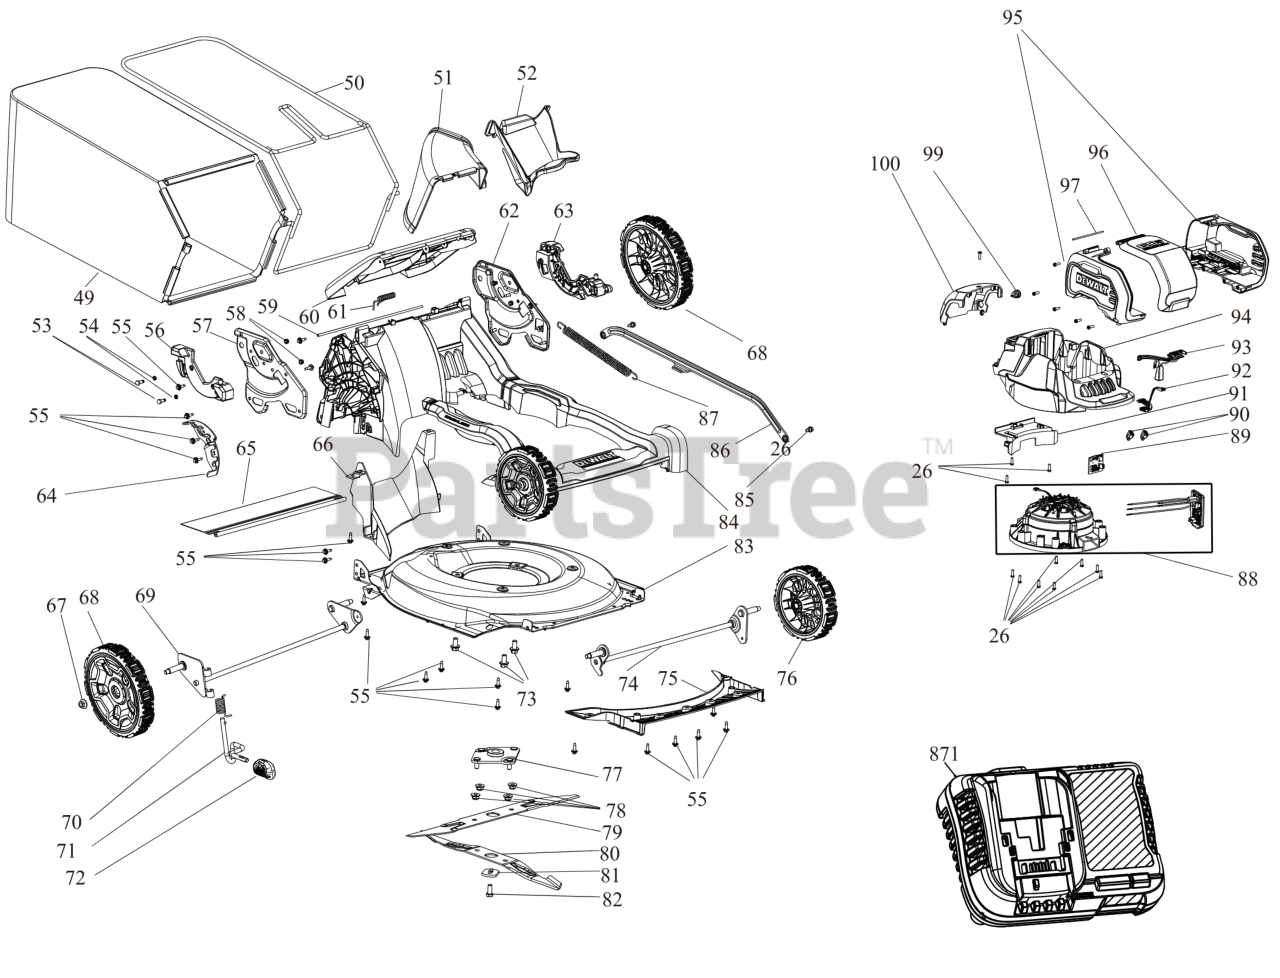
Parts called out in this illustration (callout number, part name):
1	BUTTON
2	SPRING
3	SCREW
5	COVER
6	CONTROL
8	BUTTOM
9	HANDLE SA
10	SWITCH
11	WIRE HARNESS
13	SCREW M6X45-T30-THD FRM
14	COVER
16	SWITCH COVER
17	CATCH
20	SPRING TORSION
21	STRIP
22	SLEEVE
23	TUBE UPPER
25	TUBE LOWER
26	SCREW M4.55X16 T20-PLAS THD FRM
27	SLEEVE
29	WASHER
30	SCREW
33	SPRING
35	SPRING
36	SPRING
37	SPRING
40	SPRING
43	HOLDER
44	HARNESS
45	COVER
46	BUTTON
47	COVER
49	GRASSBAG
50	FRAME
51	CHUTE
54	SPACER
55	SCREW 1/4-10 x .750
56	SUPPORT
57	BRACKET
58	LOCK-NUT
61	SPRING
62	BRACKET
63	SUPPORT
64	BRACKET
65	SHIELD
66	INSERT
67	FLANGE LOCK NUT
68	WHEEL 9X1.5
69	AXLE REAR
70	SPRING
74	AXLE FRONT
76	WHEEL SA
77	PLATE
79	BLADE MOUNT
80	BLADE MOUNT
81	WASHER
83	CUTTER DECK
87	SPRING
88	MOTOR SA
89	PCB SA
90	CONNECTOR
91	BAFFLE
92	HARNESS
93	HARNESS
94	MOTOR COVER
95	HOUSING
99	BUSHING
100	COVER
871	CHARGER
